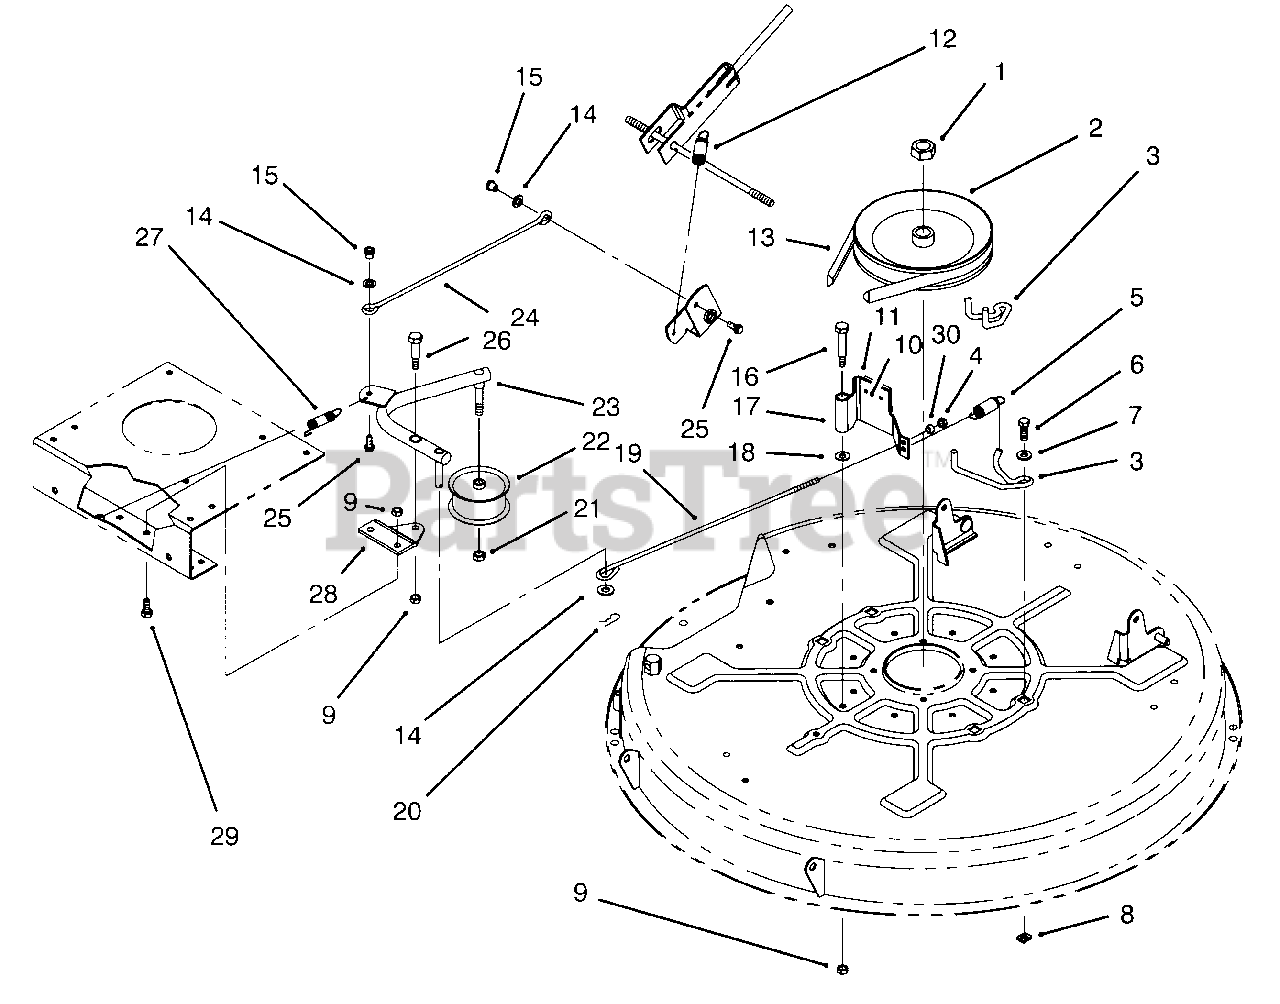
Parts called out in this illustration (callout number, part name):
1	Nut-Lock
2	Pulley-Deck
3	Guide-Belt
4	Nut-Lock
5	Spring-Extension
6	Screw-Hex Hd. Cap
7	Washer-Fender
8	Nut-Retained
9	Nut-Lock
10	Rivet-Pop
11	Pad-Brake
12	Spring/Cable Assembly
14	Washer-Flat
16	Bolt-Shoulder
17	Deck Brake Assembly(Incl Ref. #10, 11)
18	Washer-Flat
19	Rod-Deck Brake
20	Pin-Hair Cotter
21	Nut-Lock
22	Pulley-Idler
23	Arm-Idler
24	Rod-Deck Engage
25	Screw-Hex Flange Hd.
26	Bolt-Shoulder
27	Spring-Extension
28	Plate-Idler Mount
29	Screw-Hex Hd. Cap
30	Ball-Swivel
